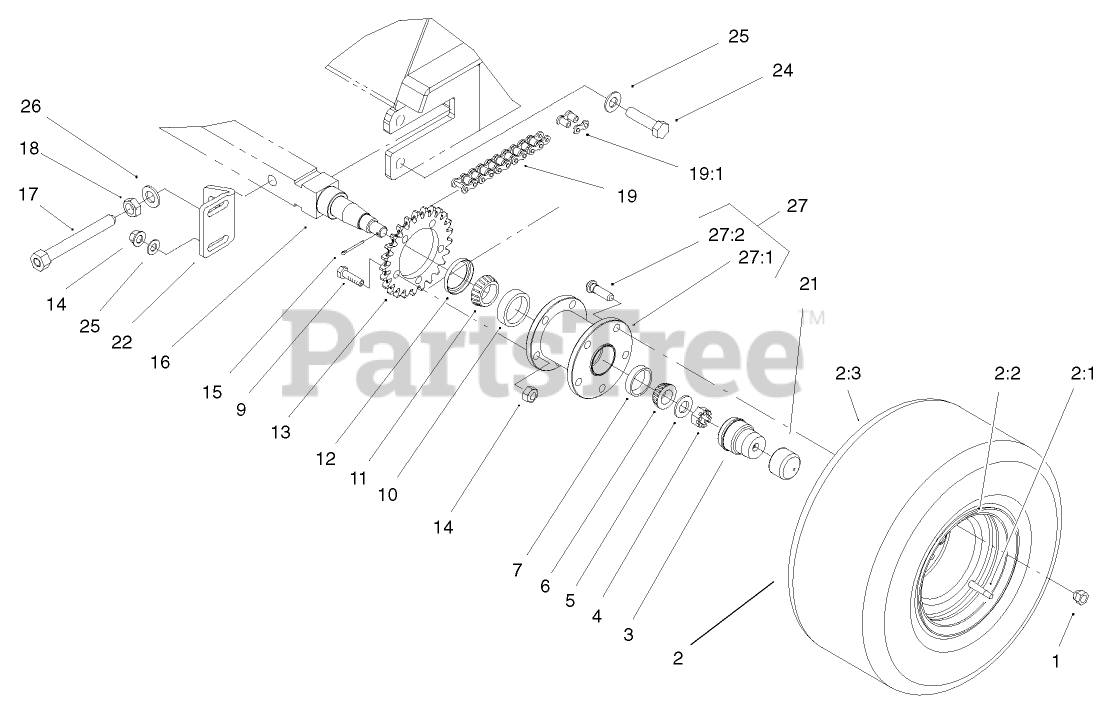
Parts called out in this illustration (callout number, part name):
1	NUT-LUG
2	ASM - WHEEL/TIRE
2:1	TUBE-TIRE
2:2	WHEEL
2:3	TURF TIRE-18 X 8.50-8
3	PROTECTOR - BEARING
4	NUT-HEX, SLOTTED
5	WASHER-FLAT
6	BEARING-CONE, TAPERED
7	BEARING-CUP, TAPERED
9	SCREW-HH
10	CUP-BEARING, TAPERED
11	CONE-BEARING, TAPERED
12	SEAL-BEARING, WHEEL
13	Sprocket-25 Tooth
14	NUT-LOCK, NI
15	PIN-COTTER
17	BOLT-TENSION
18	NUT-JAM
19	CHAIN-ROLLER
19:1	LINK-CONNECTING
21	BOOT - PROTECTOR
22	BRACKET-AXLE
24	SCREW-HH
25	WASHER-FLAT
26	WASHER-FLAT
27	FRONT HUB ASM
27:1	Hub-Front
27:2	STUD-TYPE, DRIVE
